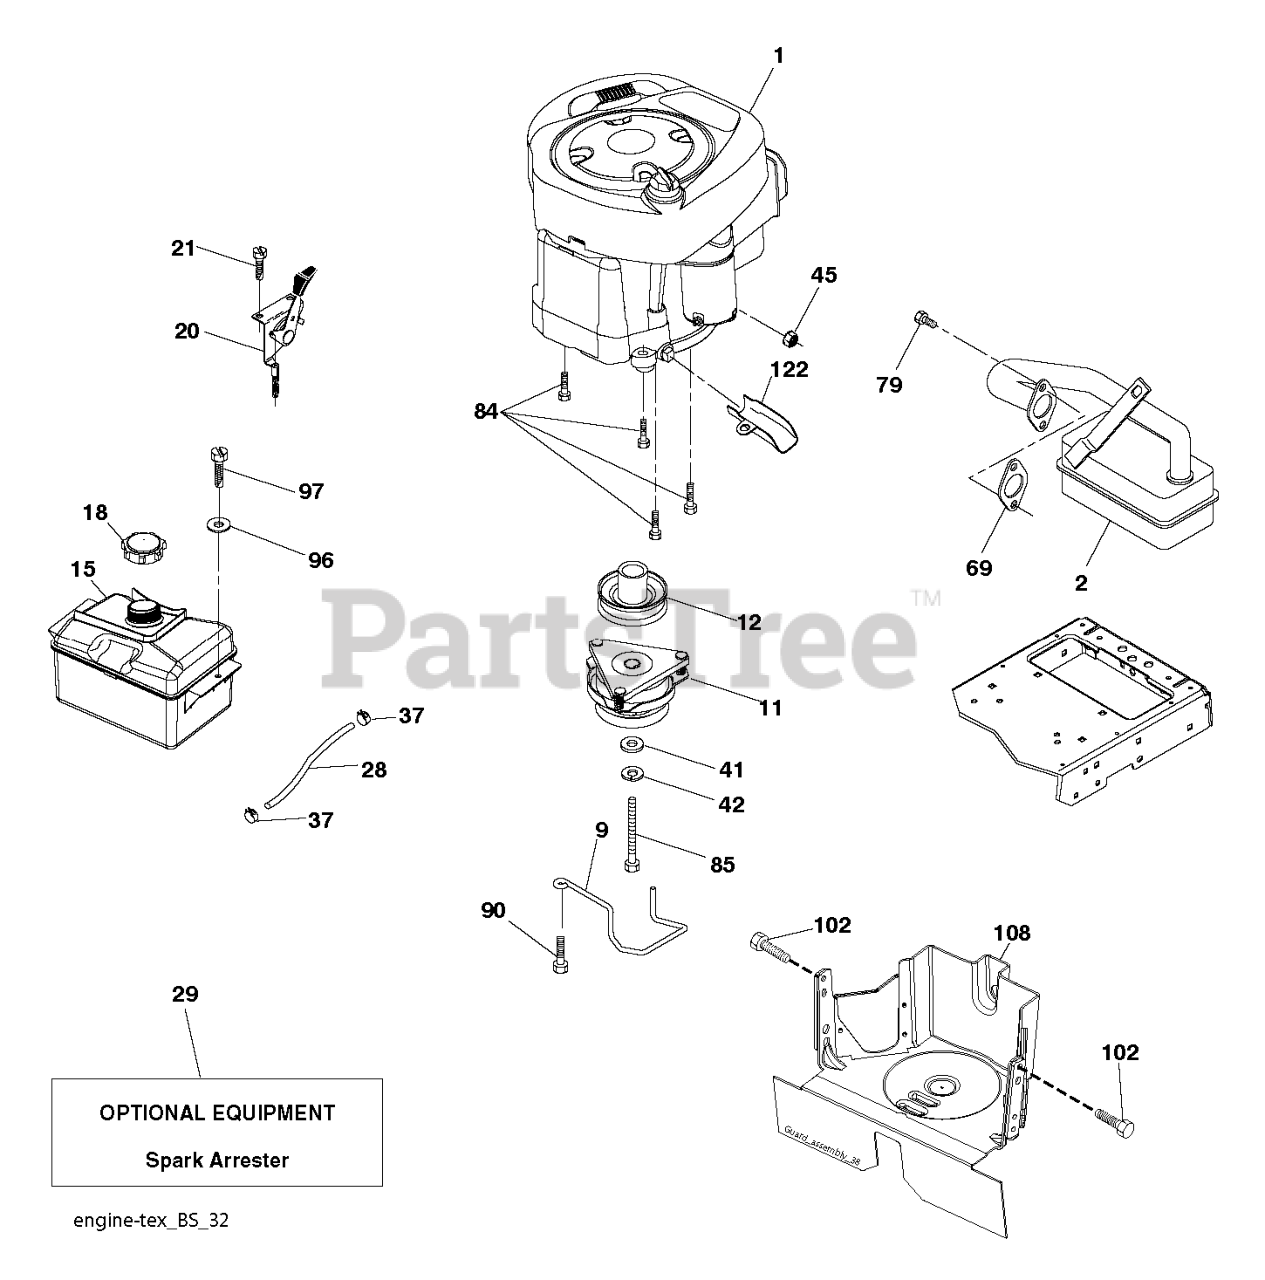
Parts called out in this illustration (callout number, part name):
2	MUFFLER.B&S.MODEL.21.11HP.OHV
9	KEEPER.BELT.ENGINE.3.25 (3 2)
11	RB.CLUTCH.OGURA.4.4.PD
12	PULLEY.ASM.ENG.OGURA.3
15	RP TANK FUEL FRT 1.5 GAL
18	CAP ASM.FUEL.2.25"FR.
20	CONTROL.TH/CK.C.
21	SCREW.#10 X 0.750.BOS
28	LINE.FUEL.20
29	KIT.SPARK ARRESTOR 794945 B&S
37	HOSE CLAMP
42	LOCKWASHER
45	NUT
69	REPL BY 532 27 22-93
79	SCREW.SOCKET HD.5/16-1
84	SCREW.3/8-16
85	BOLT HEX 7/16-20X4-1/4"
90	SCREW 3/8-16X1
96	WASHER
97	SCREW HEXWSHR 1/4-20X3/4
102	SCREW
108	COVER PULLEY
122	EXTENSION DRAIN OIL
